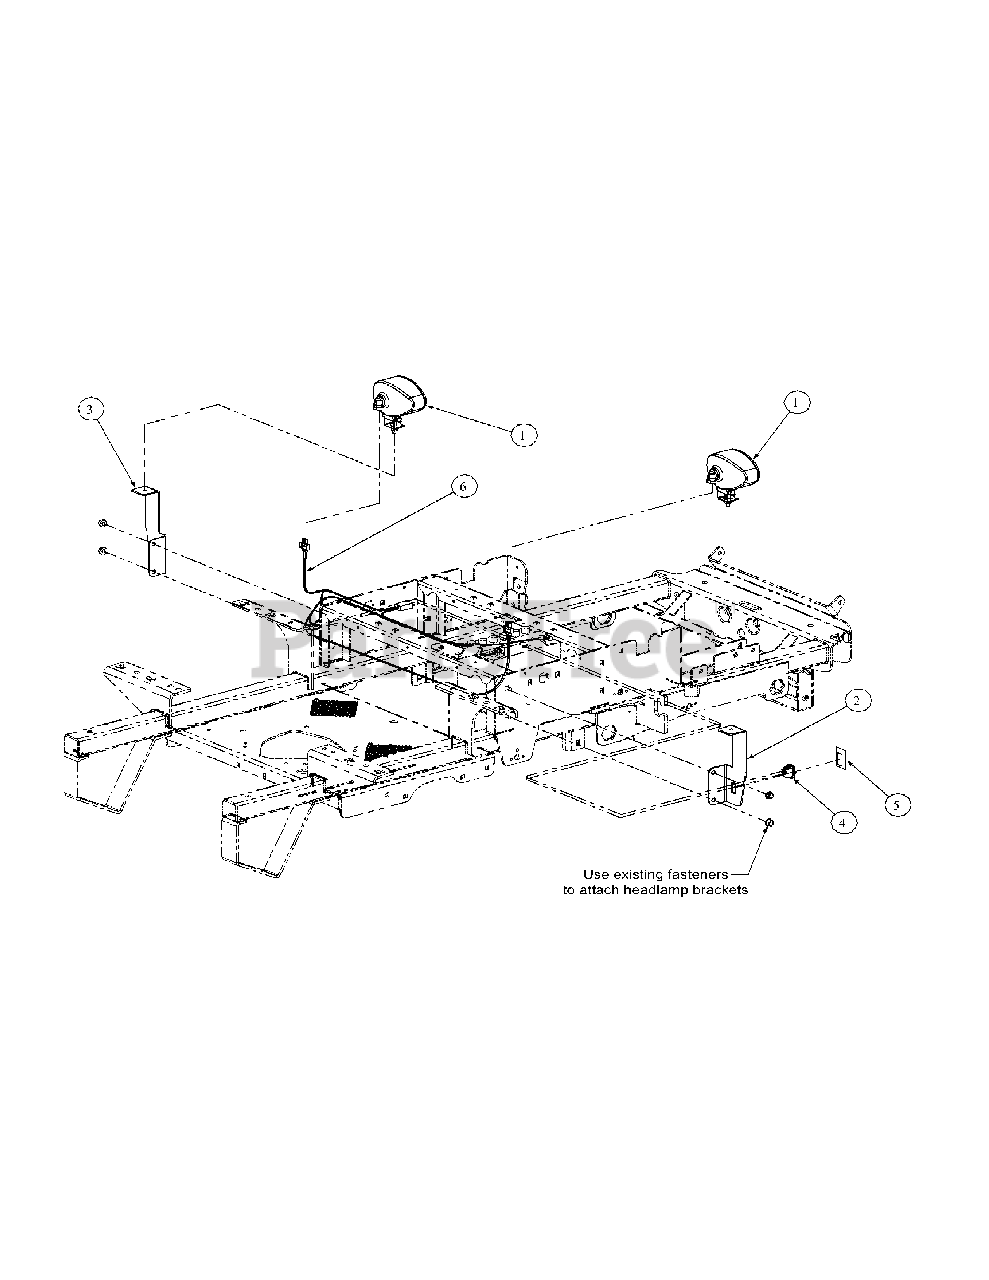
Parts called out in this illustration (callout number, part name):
1	Oval Work Lamp
2	Right Hand Lamp Bracket
3	Left Hand Lamp Bracket
4	Switch
5	Head Lamp On/Off Label
6	Wire Harness Assembly
